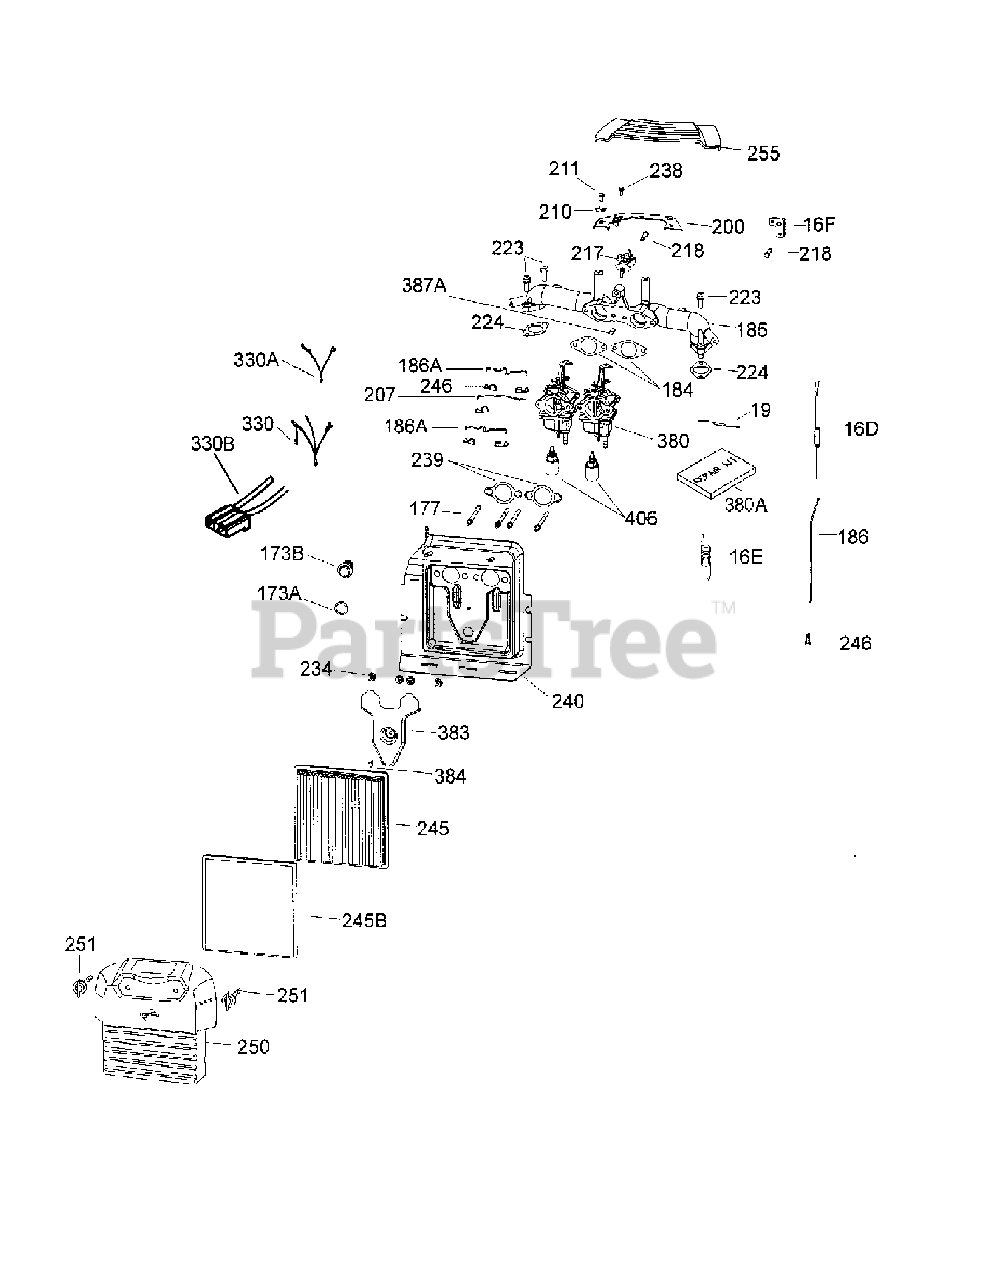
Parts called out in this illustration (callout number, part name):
16D	Governor Spring, Hi-speed
16E	Governor Idle Spring
16F	Bell Crank Lever
19	Throttle Spring
173A	Breather Tube Grommet
173B	Breather Tube Fitting
177	Carburetor Mounting Stud
184	Carburetor to Intake Pipe Gasket Kit
185	Intake Pipe (Incl. 387A)
186	Governor Link
200	Control Bracket
207	Throttle Link
210	Conduit Clip
211	Screw, 10-32 x 3/8"
217	Control Lever
218	Screw, 10-32 x 1-1/4"
223	Screw, T-30 5/16-18 x 7/8"
224	Intake Pipe Gasket (Pipe to Head) Kit
234	Lock Nut, 1/4-20
238	Screw, 10-32 x 7/16"
239	Air Cleaner Gasket Kit
240	Air Cleaner Body Ass'y. (Incl. 239)
245	Air Cleaner Filter (Paper)
245B	Air Cleaner Pre-Filter (Poly)
246	Connector Bushing Link
250	Air Cleaner Cover
251	Wing Nut, 1/4-20 x 1-19/32"
255	Control Cover
330	Fuel Solenoid Wire Assembly (R & G)
330A	Fuel Solenoid Wire Assembly (Black)
380	Carburetor (Incl. 184 & 428)
380A	Carburetor Repair Kit
383	Carburetor Baffle
384	Screw, 10-24 x 9/16" Self Tap
406	Fuel Shut-Off Solenoid
